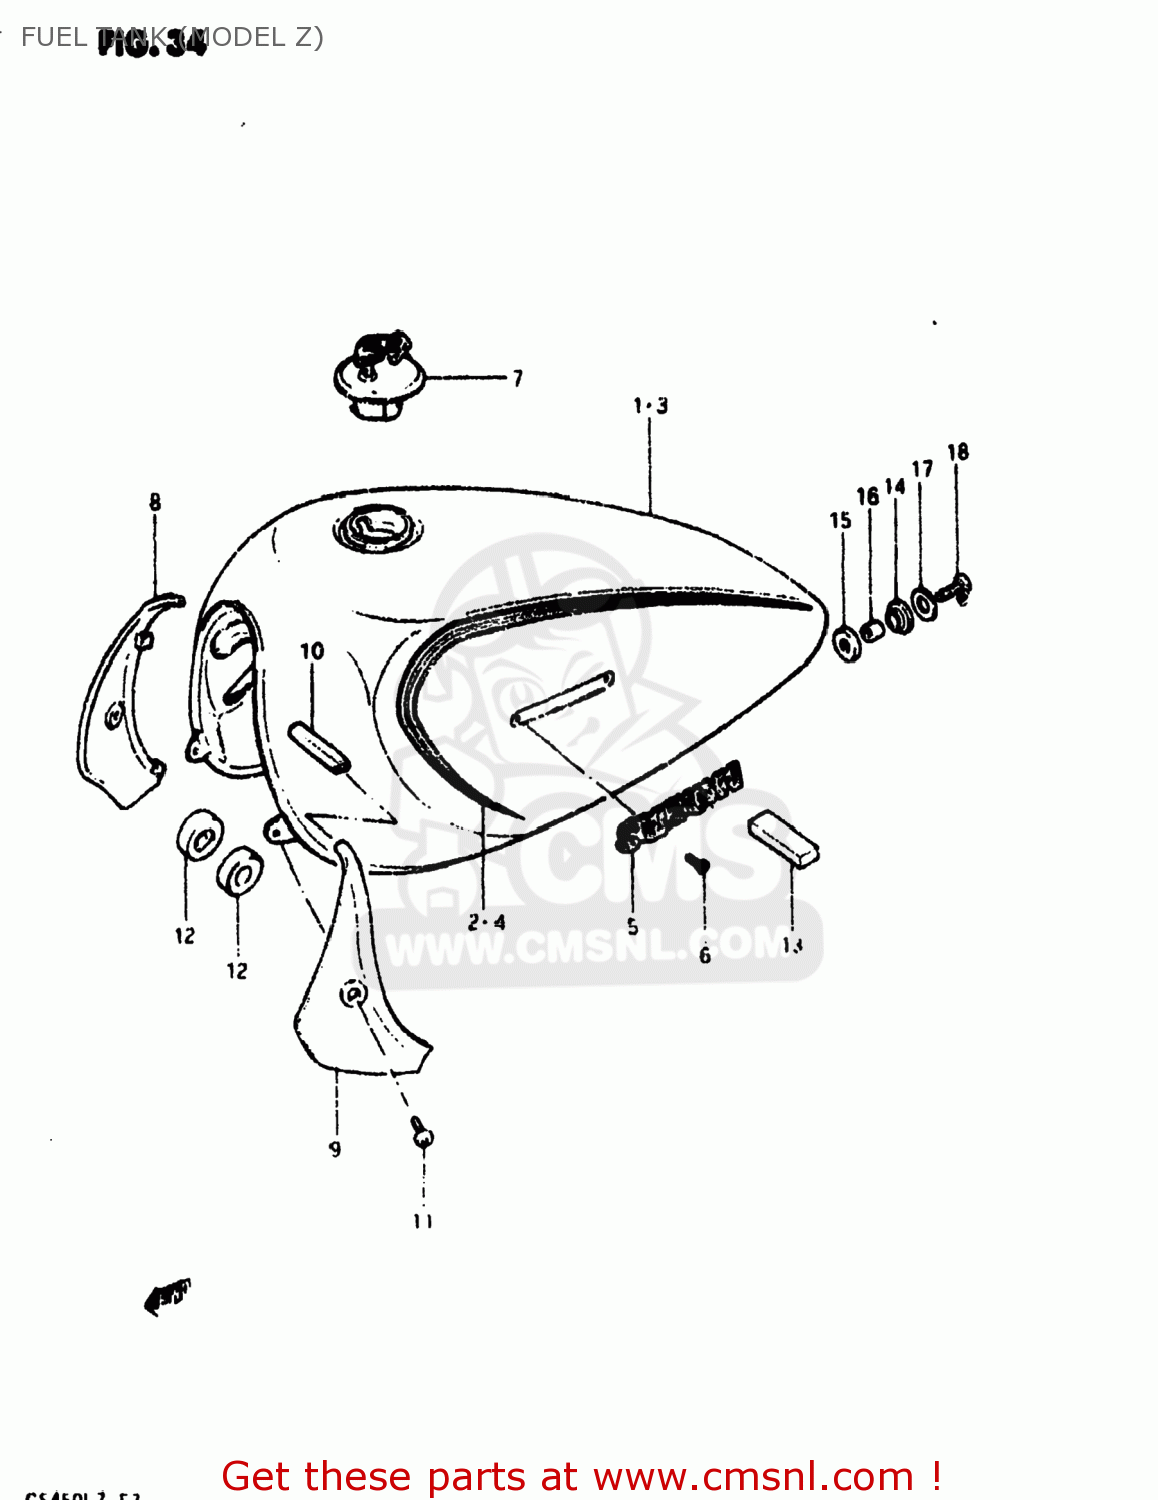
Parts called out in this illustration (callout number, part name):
1	TANK ASSEMBLY,FUEL
2	TAPE SET,FUEL TANK
3	TANK ASSEMBLY,FUEL
4	TAPE SET,FUEL TANK
5	EMBLEM,FUEL TANK
6	SCREW 3X6
7	CAP SET,FUEL TANK
8	COVER,FUEL TANK,FRONT,RIGHT
9	COVER,FUEL TANK,FRONT,LEFT
10	TUBE, FRONT
11	SCREW 6X12
12	CUSHION
13	CUSHION
14	CUSHION
15	CUSHION
16	SPACER(8.5X12X19)
17	WASHER (8.5X29X1.6)
18	BOLT (8X30)
